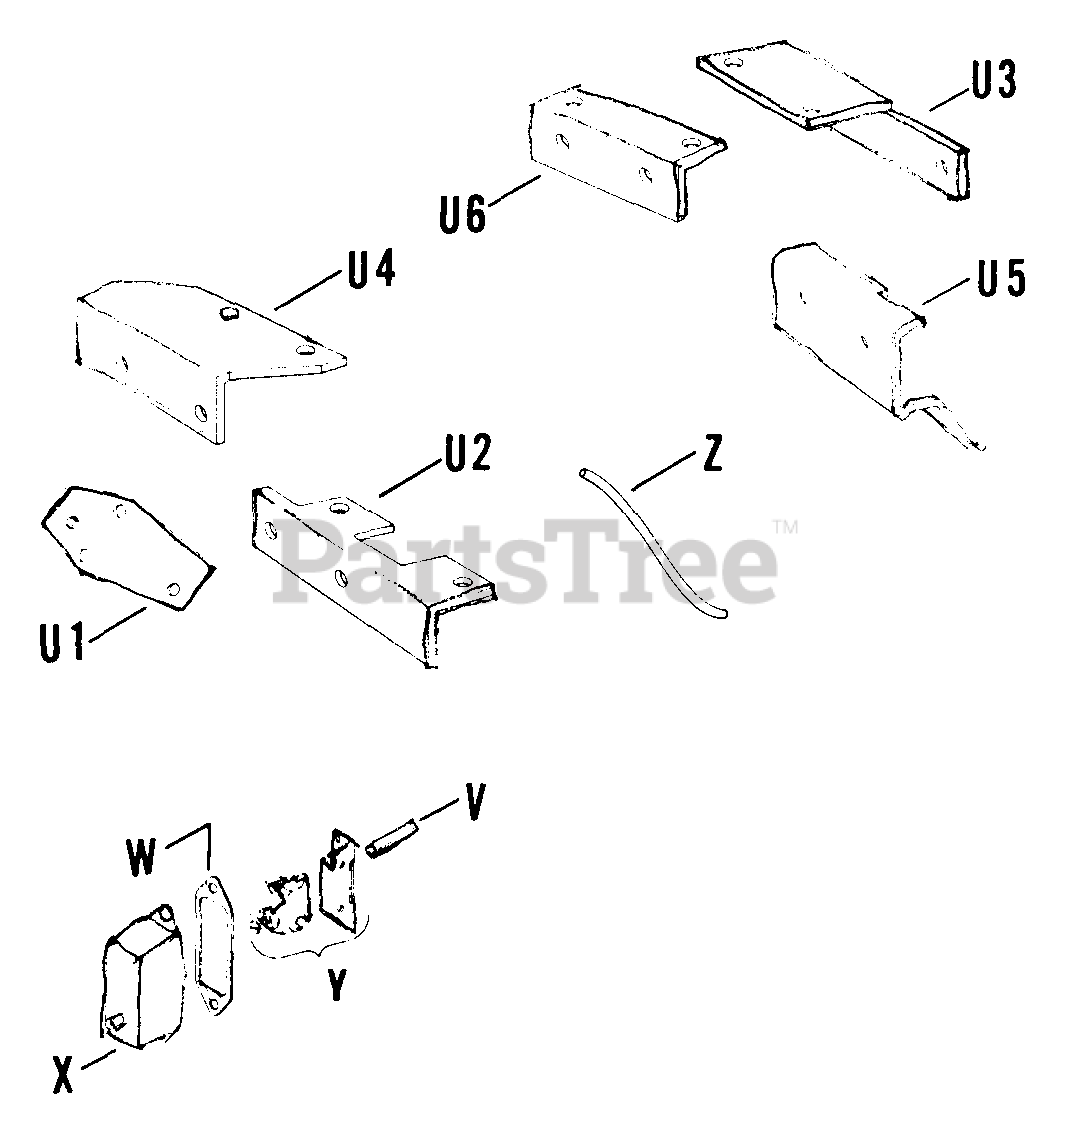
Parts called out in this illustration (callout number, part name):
W	GASKET - USE 52 041 11
X	COVER - DISCONTINUED
Y	BREAKER - USE 47 150 03
Z	INSULAT. SLEEVE - DISCONTINUED
